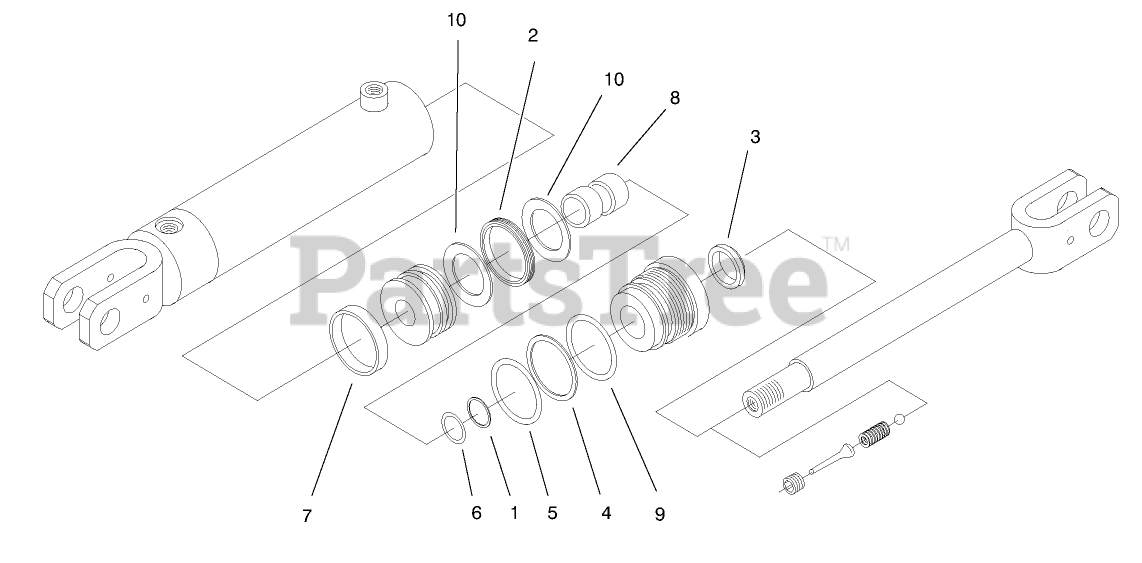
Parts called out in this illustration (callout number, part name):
1	Washer-Backup
2	Psp Seal
3	Rod-Wiper
4	Washer-Backup
5	O-Ring
6	Polypak
7	RING-WEAR
8	RING-WEAR
9	O-RING
10	Washer-Backup
